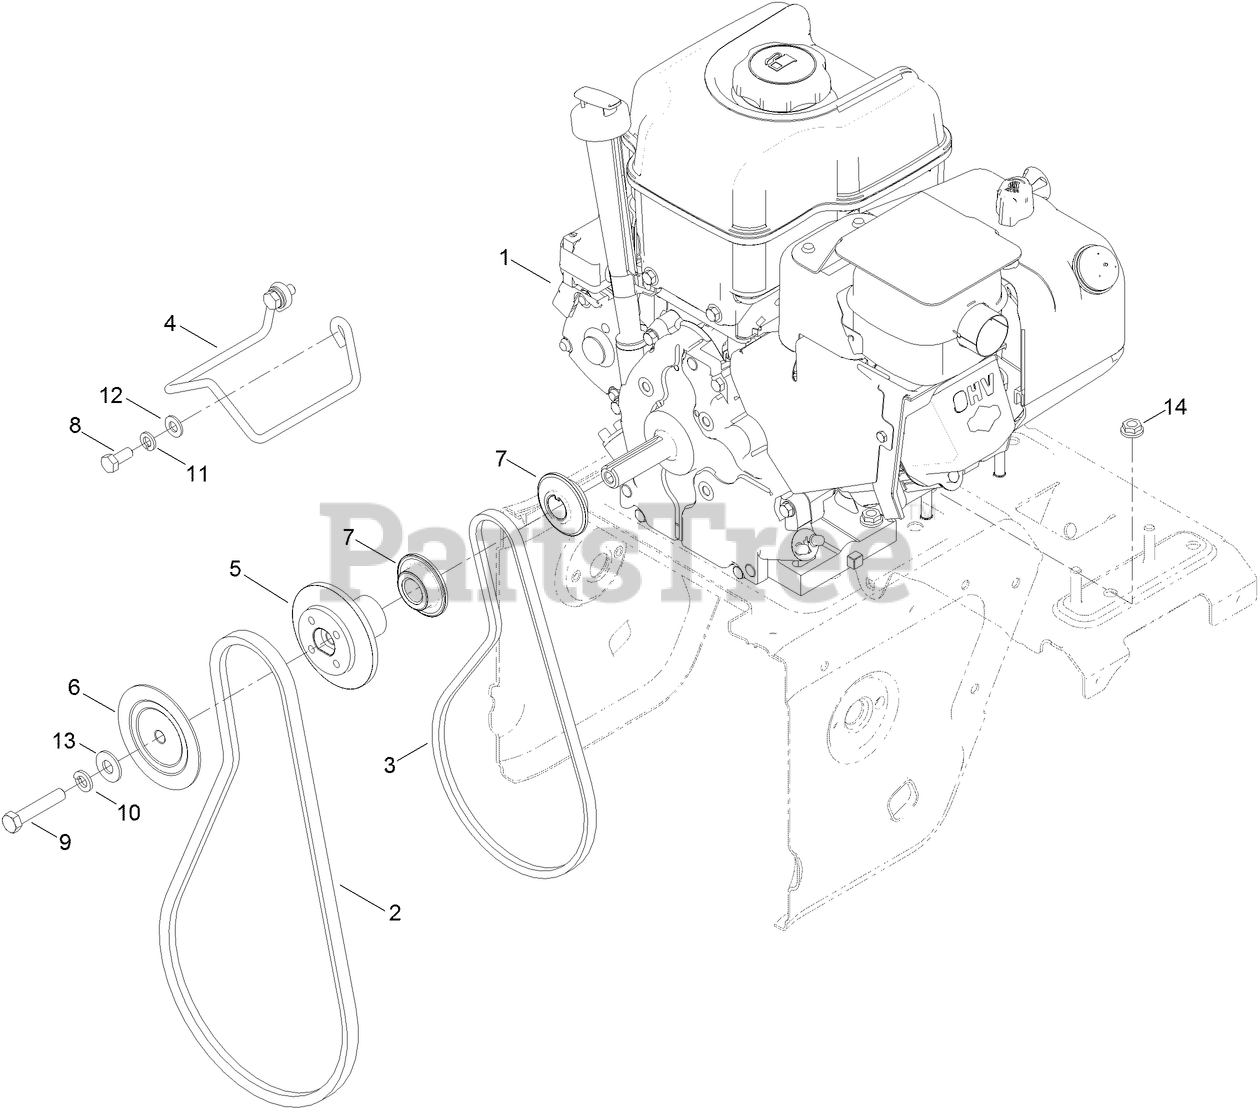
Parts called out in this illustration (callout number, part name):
2	BELT-V
3	BELT-V
5	PULLEY-AUGER, REAR
6	PULLEY-AUGER, FRONT
7	PULLEY-TRACTION
8	SCREW-HH
9	SCREW-HH
10	WASHER-LOCK
11	WASHER-LOCK
12	WASHER-PLAIN
13	WASHER-FLAT
14	NUT-HF
